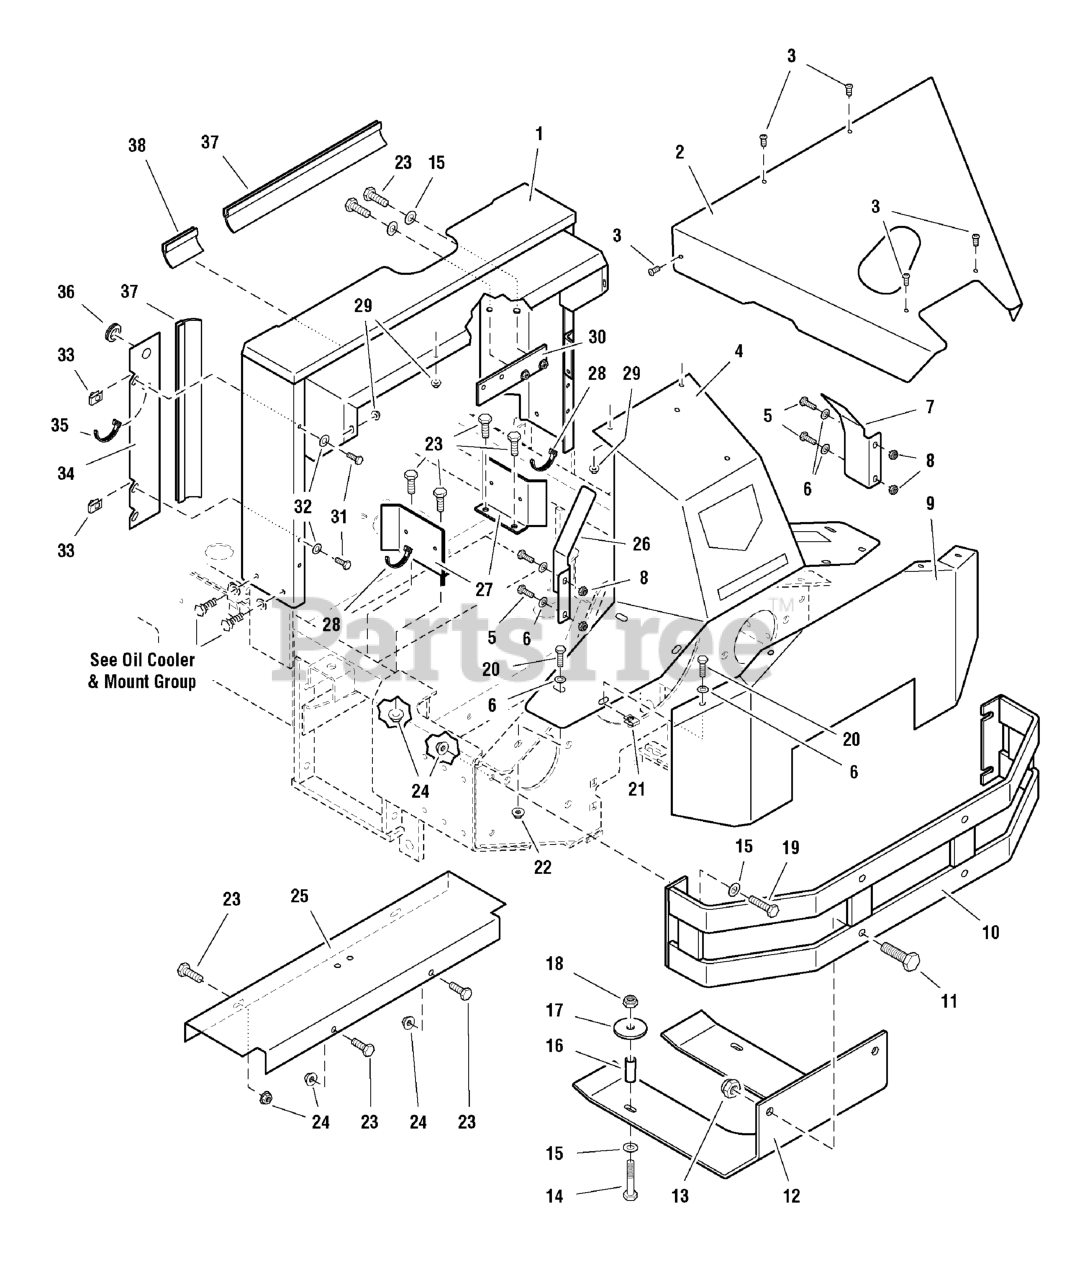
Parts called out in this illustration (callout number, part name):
1	RADIATOR SHROUD
4	REAR HOOD SUPPORT
5	BOLT, 5/16-18 X 3/4 GD5
6	WASHER, 5/16" SAE
7	FLYWHEEL GUARD-RH
8	NUT, 5/16-18 Hex Nylon Lock
9	REAR SHIELD
11	BOLT, 1/2-20 X 1-1/2, GD5 CZ
12	SKID SHIELD
13	NUT, Hex, Nylon Lock, 1/2-20
14	BOLT, 3/8-16 X 2-1/2" GD5 CZ
15	WASHER, 3/8 SAE
16	SPACER, .38 x .50 x 1.56
17	WASHER, 3/8 x 1-3/4
18	NUT, 3/8-16 HEX NYLON LOCK
19	BOLT, 3/8-16 X 1-1/4" GD5 CZ
20	BOLT, 5/16-18 X 1 GD5 YZ
21	BODY CLIP, 5/16-18-7GA MATERIAL
22	NUT, 5/16-18 HEX SERRATED FLANGE (SMALL)
23	BOLT, 3/8-16 X 1" GD5 CZ
24	NUT, 3/8-16 Hex Serrated Flange
25	DEBRIS SHIELD
26	FLYWHEEL GUARD-LH
27	SUPPORT PLATE
28	TIE WRAP, 11"
29	NUT, 1/4-20 Hex Nylock Flange
30	MOUNT, Water Separator
31	BOLT, 1/4-20 x 3/4
32	WASHER, 1/4 SAE
33	BODY CLIP, 1/4-20
34	SIDE BAFFLE
35	TIE WRAP, 5-1/2"
36	GROMMET, 1/2"
37	WIPER SEAL, 17"
38	WIPER SEAL, 3"
